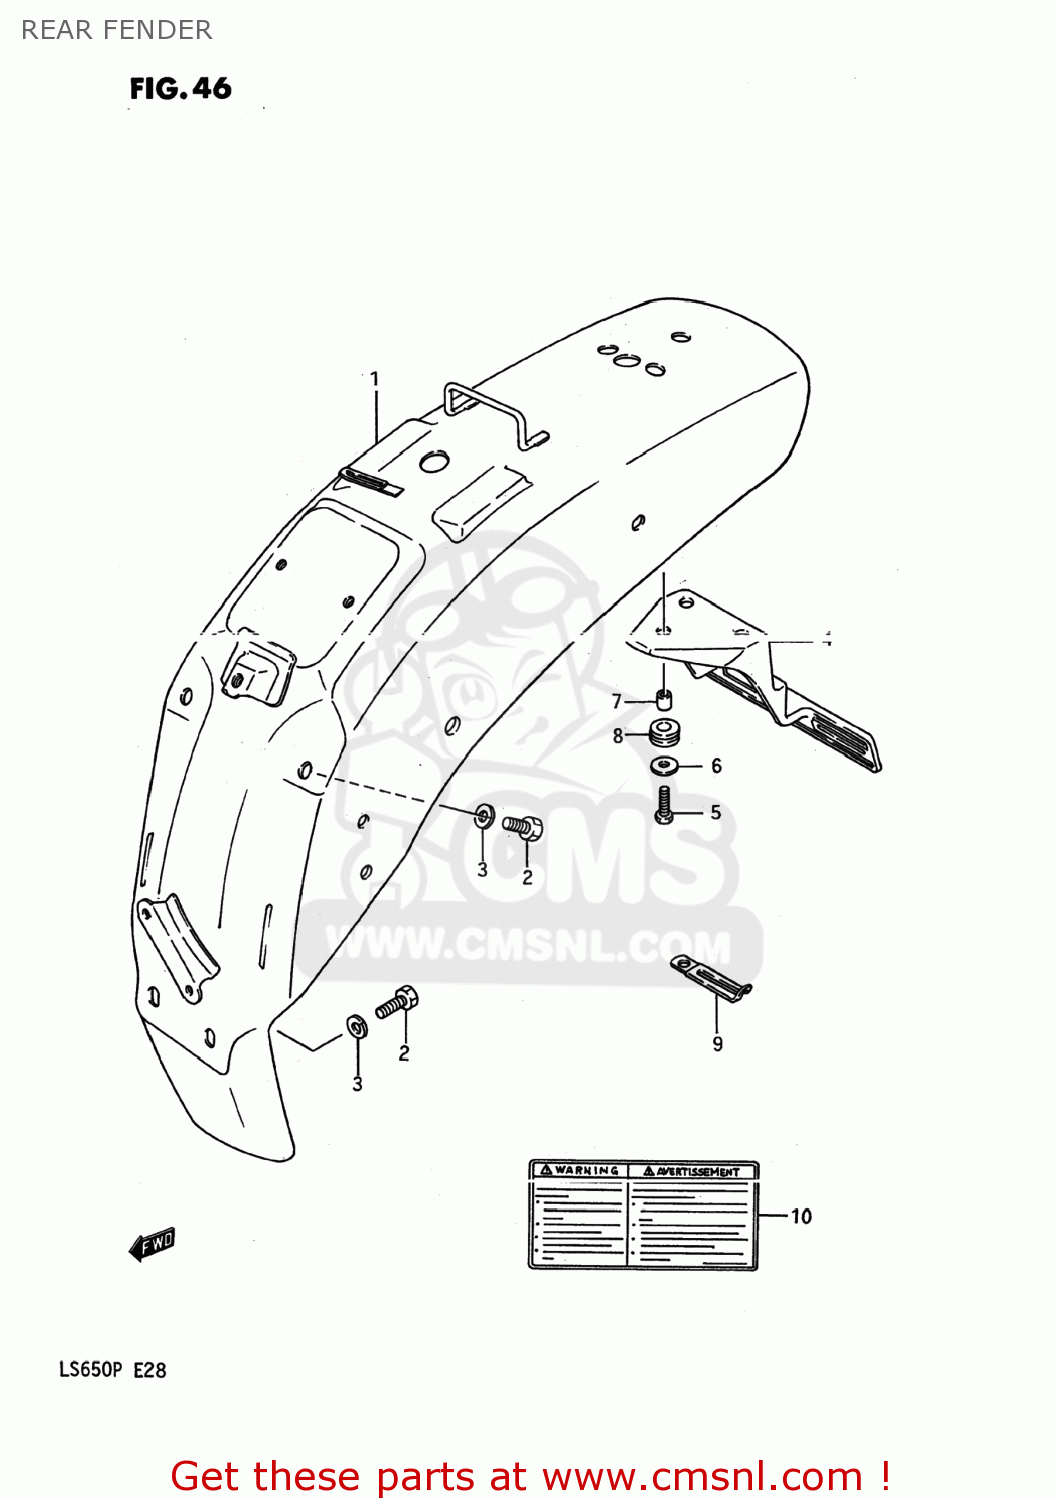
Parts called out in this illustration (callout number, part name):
1	FENDER,REAR
2	BOLT 8X25
3	WASHER 8MM
4	BRACKET,LICENSE PLATE
5	BOLT
6	WASHER
7	SPACER (6.1X9X9)
8	CUSHION
9	CLAMP L:35
10	LABEL,GENERAL WARNING
11	LABEL (TIRE AIR PRESSURE)
